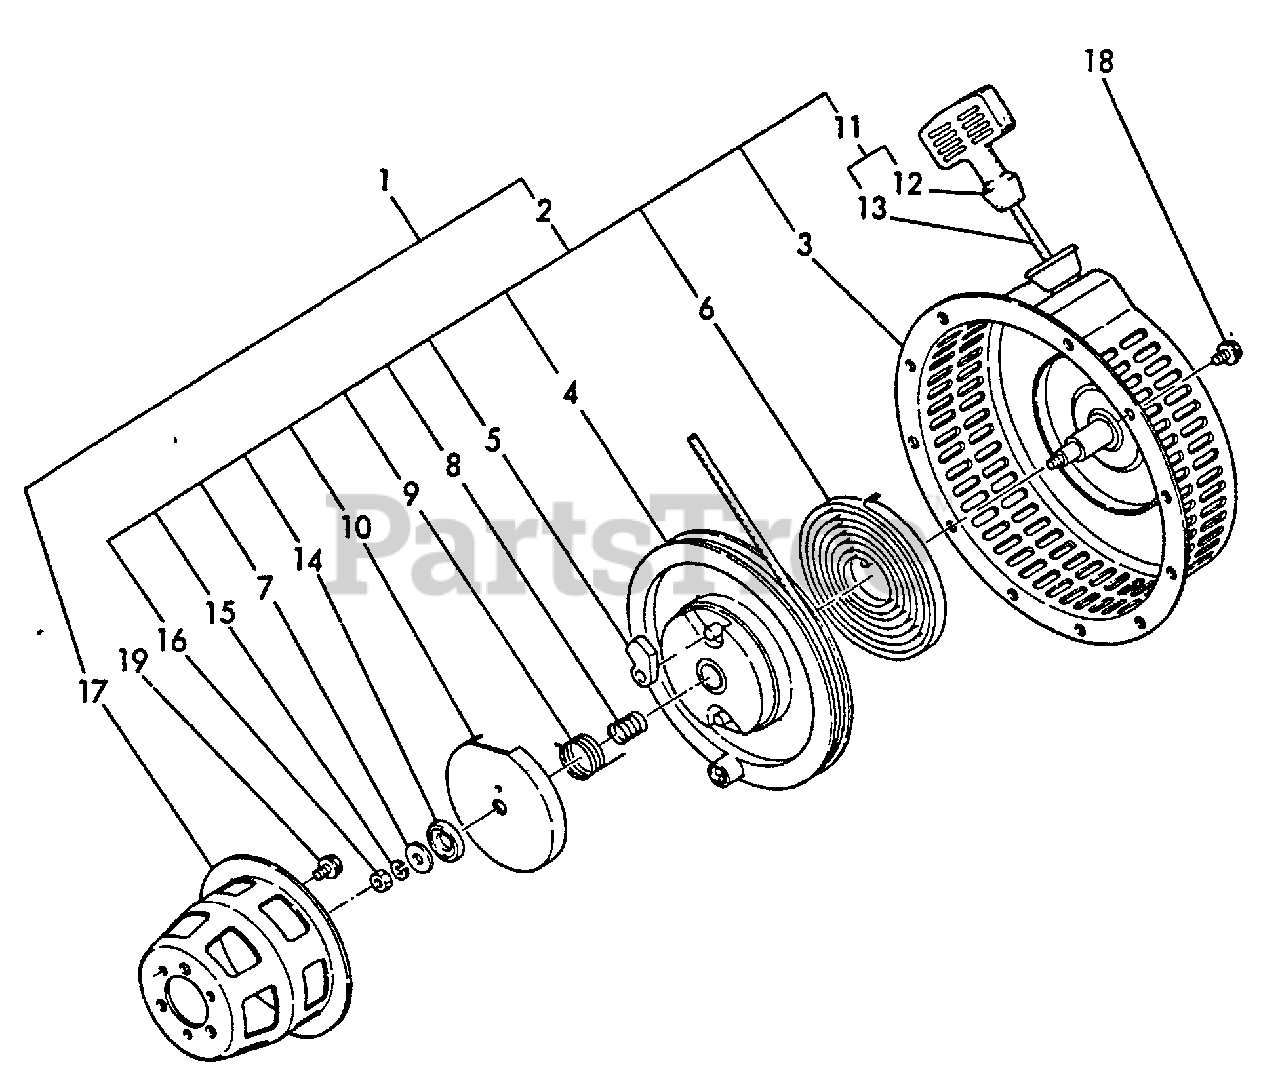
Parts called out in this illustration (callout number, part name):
1	STARTER ASSY, RECOIL
2	STARTER ASSY, RECOIL
3	CASE, STARTER
5	RATCHET
6	SPRING
7	WASHER, THRUST
8	SPRING, FRICTION
9	SPRING, RETURN
10	PLATE, FRICTION
11	STARTER ROPE ASSY
12	GRIP, STARTER
13	ROPE, STARTER
14	WASHER, THRUST
15	LOCKWASHER - 6
16	NUT - 6
17	REEL, ROPE
18	BOLT - 6×8 -- PLATED
19	BOLT - 6×12 -- PLATED
